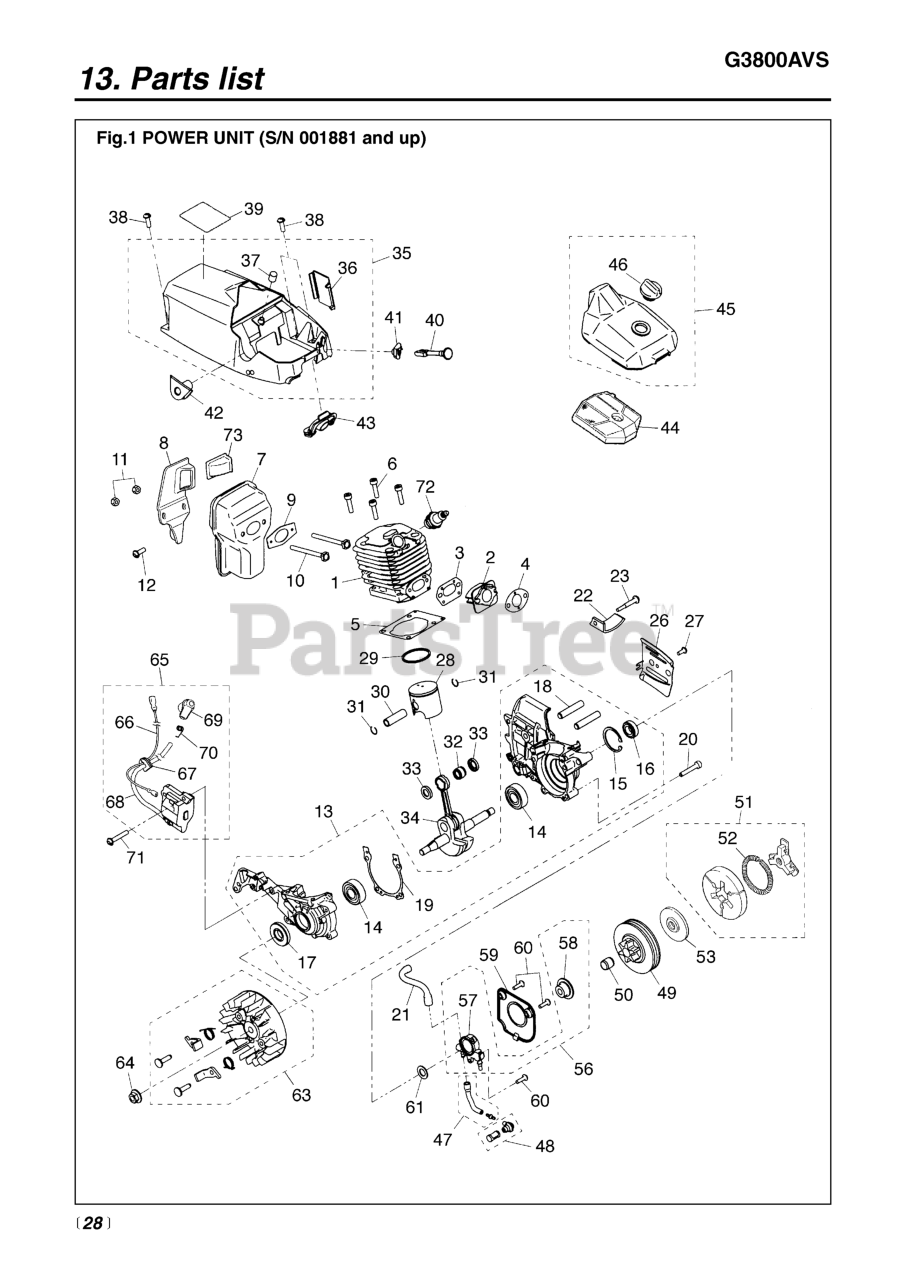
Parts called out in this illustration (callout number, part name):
1	CYLINDER
2	INSULATOR
3	GASKET, INLET (RPLS-14122)
4	GASKET
5	GASKET, CYLINDER
6	BOLT (RPLS 2850-14220)
7	MUFFLER
8	STAY
9	GASKET, MUFFLER
10	BOLT, MUFFLER
11	NUT, MUFFLER (RPLS 3356-15230
12	SCREW (REPLACES 2616-24320)
13	CRANKCASE ASSY
14	BEARING
15	RING, SNAP, M32 x 1.2
16	SEAL, OIL (RPLS 1100-21210)
17	SEAL
18	STUD (RPLS 0205-50825)
19	GASKET, CASE
20	BOLT
21	PIPE
22	CATCHER
26	PLATE (A)
28	PISTON
29	RING, PISTON
30	PIN, PISTON
31	RING, SNAP
32	BEARING
33	WASHER
34	SHAFT COMPLETE
35	COVER COMPLETE
38	SCREW
39	LABEL
40	ROD, CHOKE
41	GROMMET, CHOKE
42	GROMMET
43	GROMMET, THROTTLE
44	CLEANER, AIR COMP
45	COVER, CLEANER COMP
46	KNOB (RPLS 3356-83322)
47	PIPE IN COMP.
48	FILTER COMPLETE
49	DRUM, CLUTCH
50	BEARING
51	CLUTCH ASSEMBLY
52	SPRING
53	PLATE
56	OIL SUPPLIER ASSY.
57	PUMP, OIL (RPLS. T2100-55110)
58	WORM GEAR
59	COVER, PUMP
60	SCREW
61	WASHER
63	ROTOR COMPLETE
65	COIL COMPLETE
67	GROMMET
68	CORD
69	CAP, PLUG
70	SPRING PLUG (RPLS 3310-71320)
71	SCREW
72	PLUG, SPARK, RCJ7Y
73	ARRESTER, SPARK
